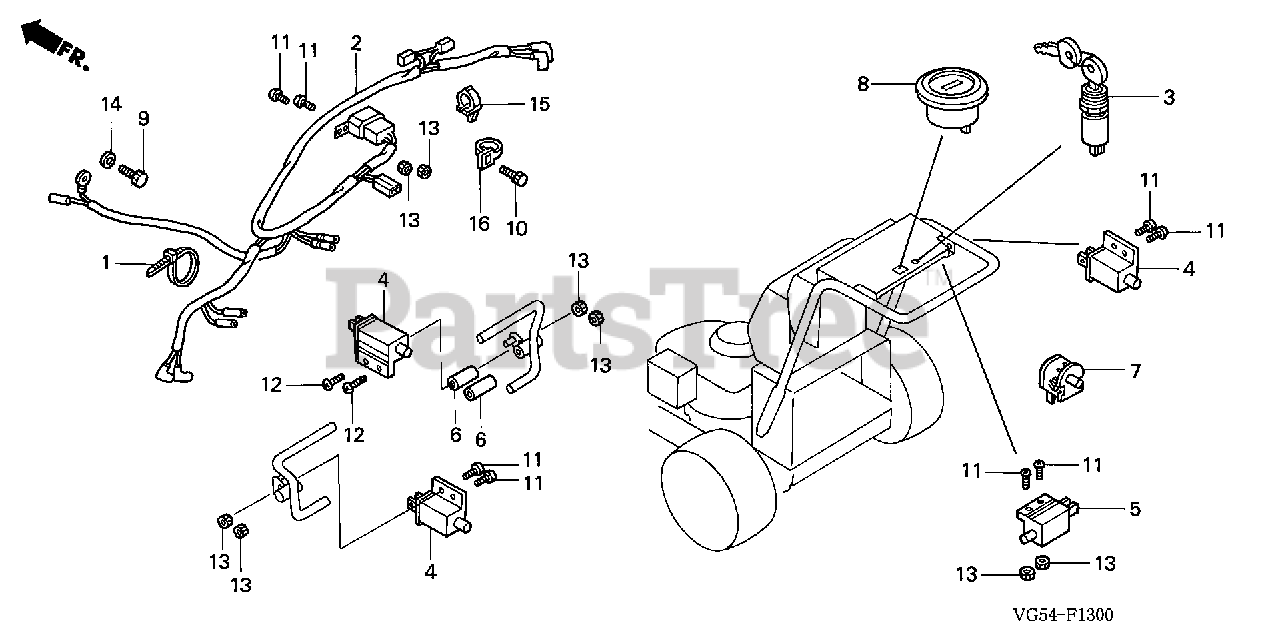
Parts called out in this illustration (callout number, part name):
2	WIRE HARNESS ASSY.
3	SWITCH ASSY., COMBINATION
4	SWITCH, LIMIT
5	SWITCH, LIMIT (REVERSE)
6	SPACER, SWITCH
7	SWITCH, PTO
8	METER ASSY., HOUR
9	BOLT, HEX. (8X1.25-16)
10	BOLT, HEX. (5/16-18X3/4")
11	SCREW, PAN (10-24X5/8")
12	SCREW, PAN (10-24X1 1/2")
13	NUT (10-24)
14	WASHER, LOCK
15	CLIP A, WIRE HARNESS
16	CLIP B, WIRE HARNESS
